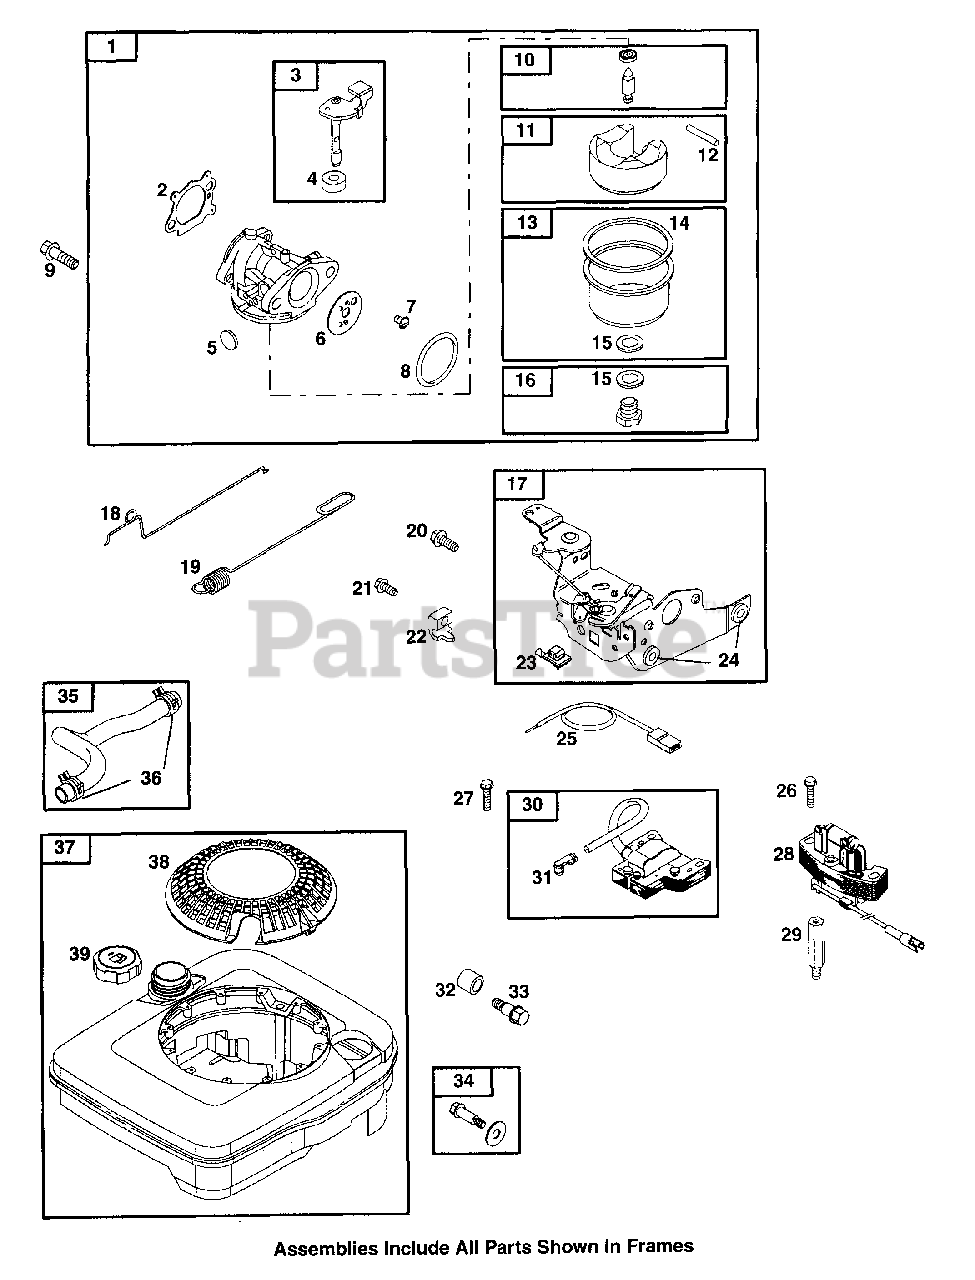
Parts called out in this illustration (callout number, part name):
1	Carburetor
2	Air Cleaner Gasket
3	Throttle Shaft
4	Choke/Throttle Dust Seal
5	Welch Plug
6	Throttle Valve
8	O-Ring Seal (Intake Manifold)
9	Screw (Carburetor)
10	Needle/Seat Kit
11	Carburetor Float
12	Float Hinge Pin
13	Float Bowl
14	Float Bowl Gasket
15	Sealing Washer
16	Main Jet (Standard)
17	Control Bracket
18	Mechanical Governor Link
19	Governor Spring
20	Screw (Control Bracket)
21	Screw (Casing Clamp)
22	Casing Clamp
23	Stop Switch
24	Spacer
27	Screw (Magneto Armature)
28	Alternator
30	Magneto Armature
31	Sparkplug Terminal
32	Fuel Tank Spacer
33	Screw (Fuel Tank)
34	Screw/Washer Kit
35	Fuel Line (Molded)
36	Hose Clamp
38	Rewind Guard
39	Fuel Tank Cap
